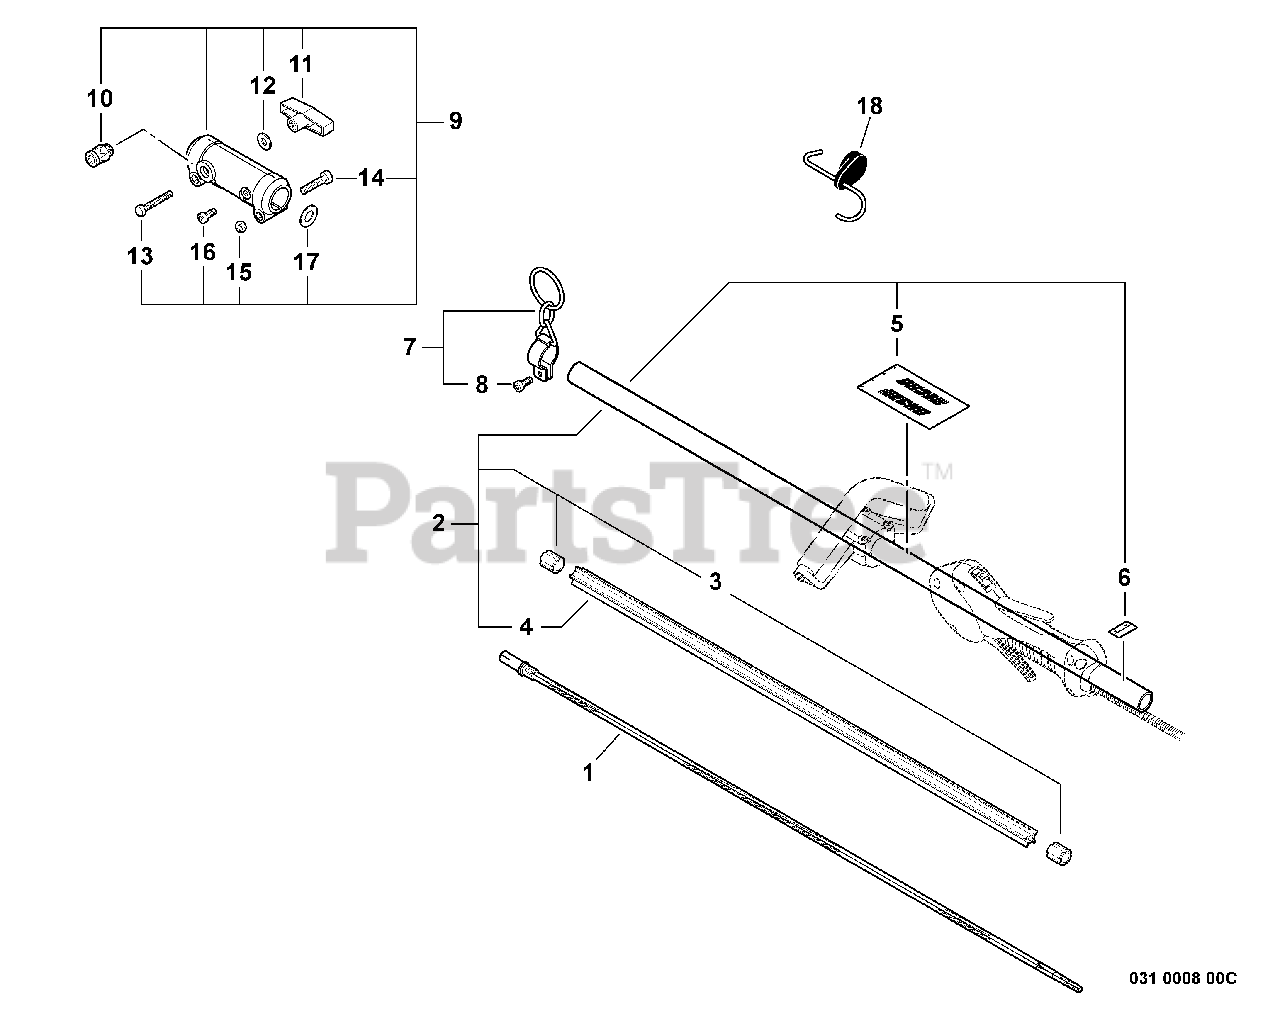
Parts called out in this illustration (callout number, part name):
1	DRIVESHAFT - FLEXIBLE
2	MAIN PIPE ASSY
4	LINER - FLEXIBLE
5	LABEL, HANDLE LOCATION
6	LABEL - ALIGNMENT
7	HANGER SET, HARNESS
8	BOLT, TORX 5×12
9	COUPLER ASSY
10	LATCH ASSY
11	KNOB, FASTENER
12	WASHER 6.6×20×1.6
13	BOLT 6×40
14	BOLT, TORX 6×25
16	BOLT, TORX 5×10
17	WASHER 18 SPR STEEL
18	HANGER, ATTACHMENT
